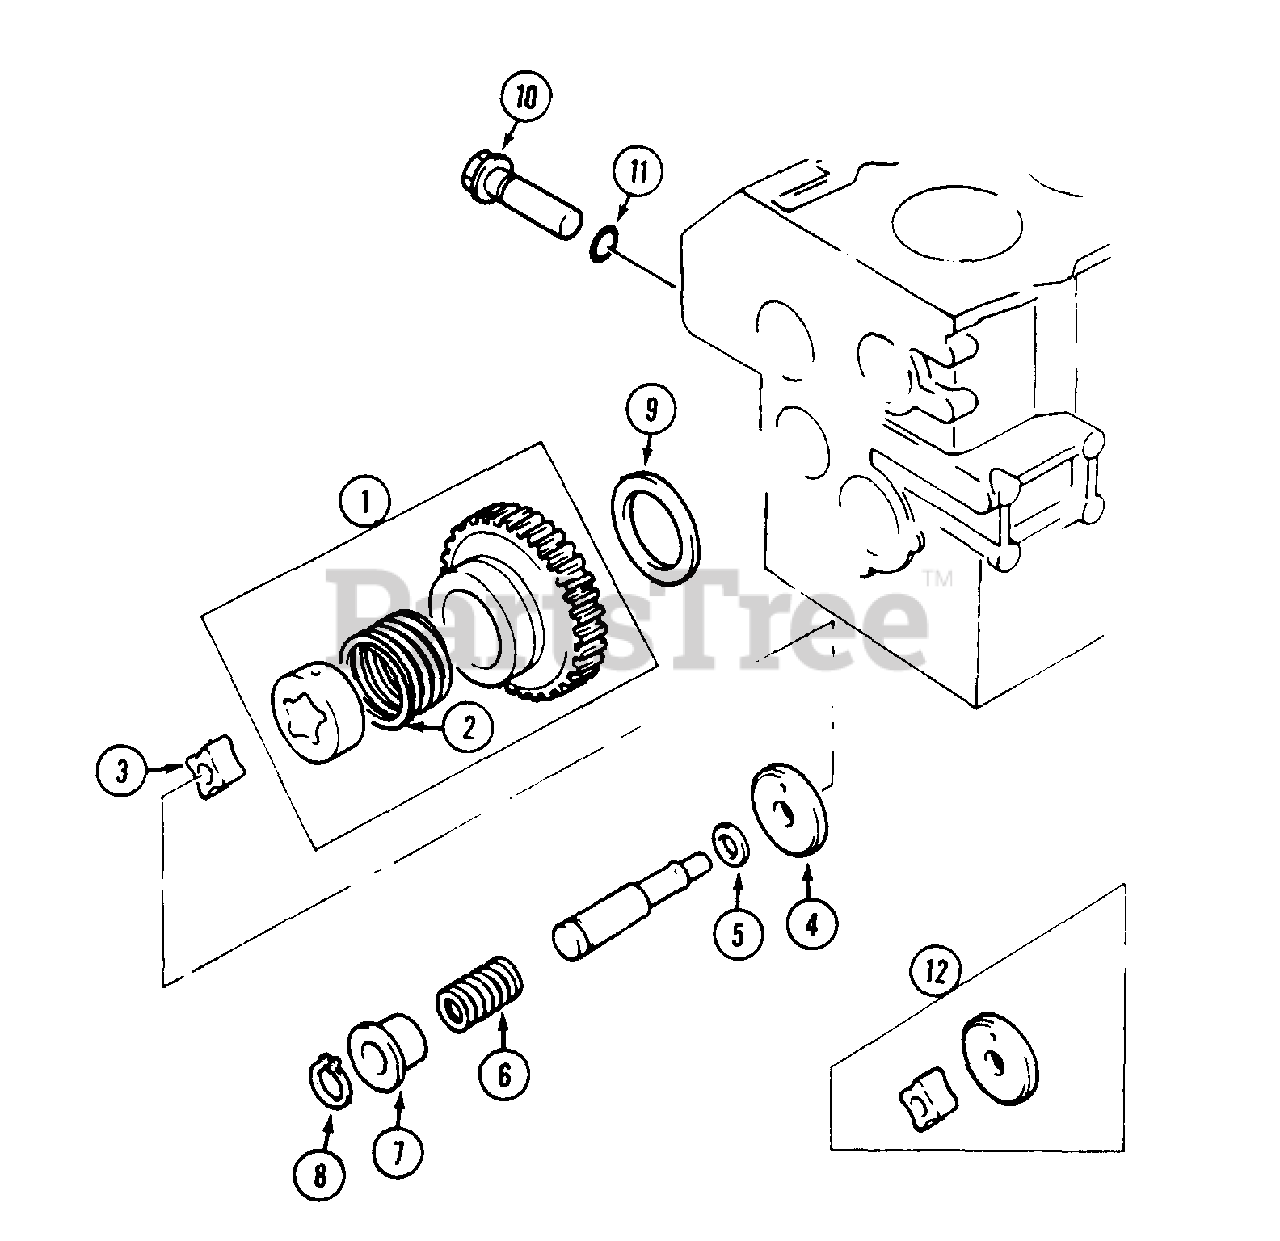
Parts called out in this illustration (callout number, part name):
1	GEAR ASSEMBLY
2	SPRING
3	ROTOR
4	COVER
5	SHIM - 0.10mm
6	SPRING
7	COLLAR
8	CIRCLIP
9	WASHER
10	VALVE
11	"O" RING
12	KIT - repair
